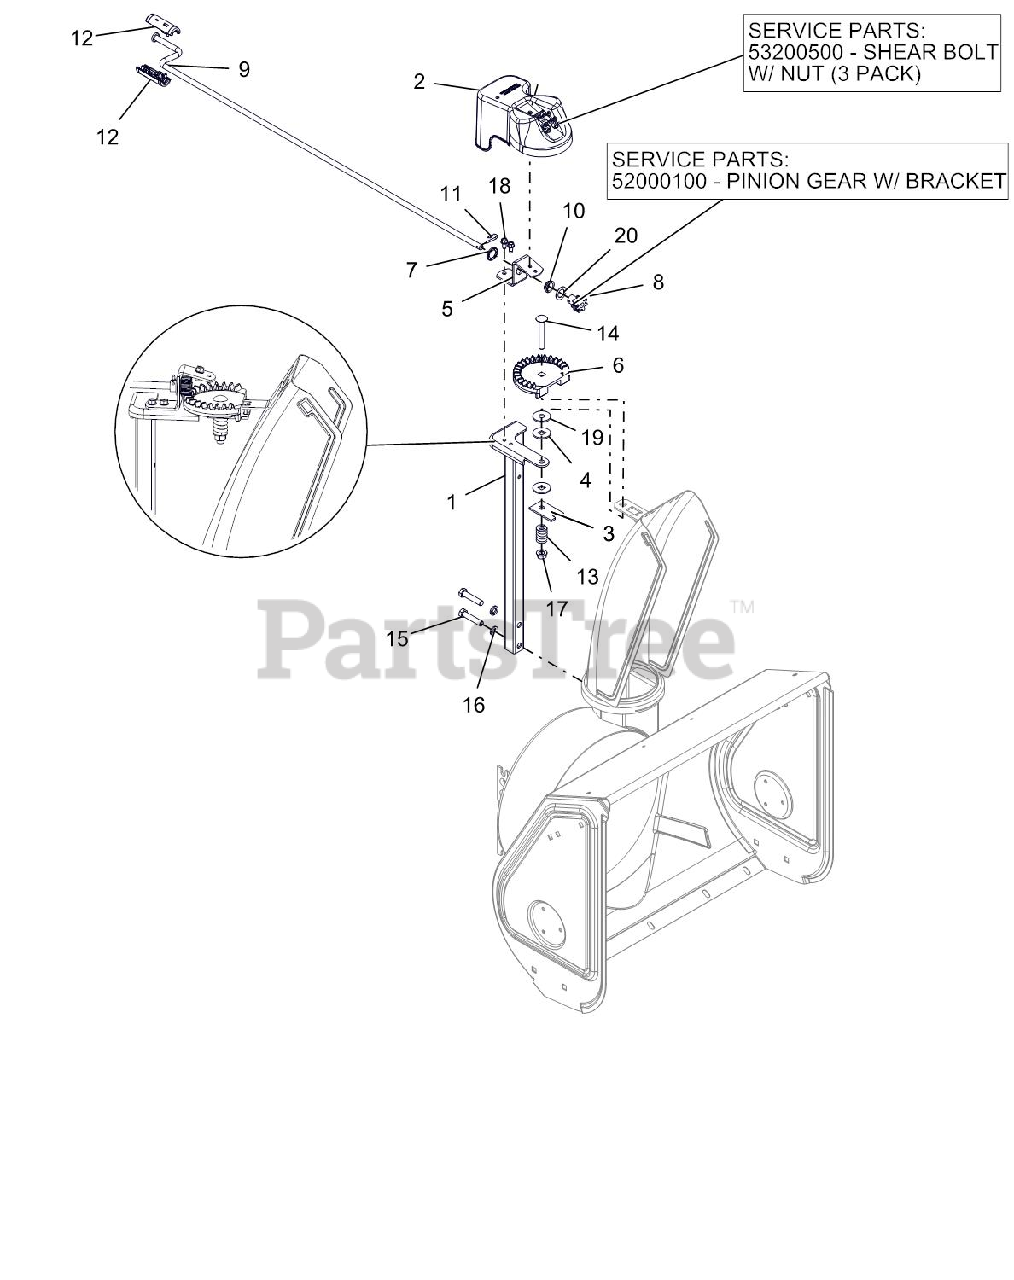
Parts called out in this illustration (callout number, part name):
1	CHUTE PEDESTAL, TALL COMPACT
2	SHEAR BOLT WITH NUT
2	GEAR COVER ASSY SM SHEAR BOLT
3	PLATE, FRICTION
4	FRICTION WASHER
5	BRACKET, PINION GEAR
6	CHUTE GEAR
7	PUSHNUT .625
8	PINION GEAR - CHUTE
9	ROD, CHUTE CRANK, COMP&SNOTEK
10	BUSHING, POLYLINER-.63 SNAPIN
11	PIN, SPRING CLIP
12	KNOB,CRANK-SNAP COMPACT-GRAY
13	SG-COMP .187X.56X1.62
14	@BLT-RDHDSQNK .38-16X2.50 G5YZ
15	@BLT-HEX .38-16X1.75 GR5 YWZC
16	@WSHR-LK .38X.094 REG YWZC
17	@NUT-LK-TOP-FLG .38-16 YWZC
18	SCR-TAP .25-20X.50 HWH TR YWZ
19	@WSHR-FL-STL .406X1.25X.10 ZC
20	WSHR-THRST .625 X 1.0 X .03
21	PINION GEAR W/BRACKET
